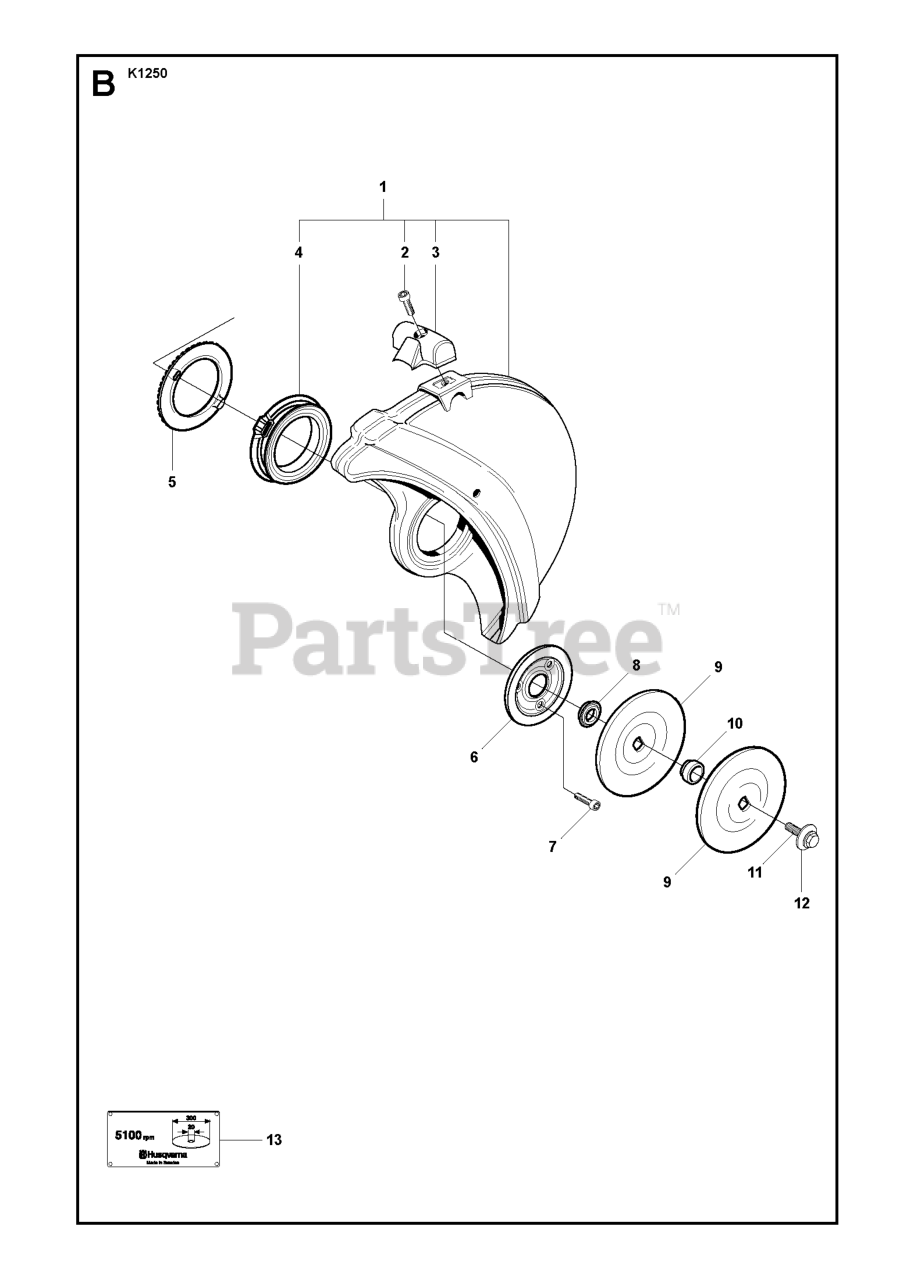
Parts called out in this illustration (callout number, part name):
1	PROTECTOR
1	RP GUARD
2	SCREW MC6S 5X20
7	SCREW MC6S 5X16
8	SLEEVE
9	WASHER
10	BUSHING-30MM
11	WASHER
13	Arbor Size Decal/22.2 Dia. - 16"
13	ARBOR SIZE DECAL/25.4
13	ARBOR SIZE DECAL/20
13	Arbor Size Decal/22.2 Dia. - 14"
